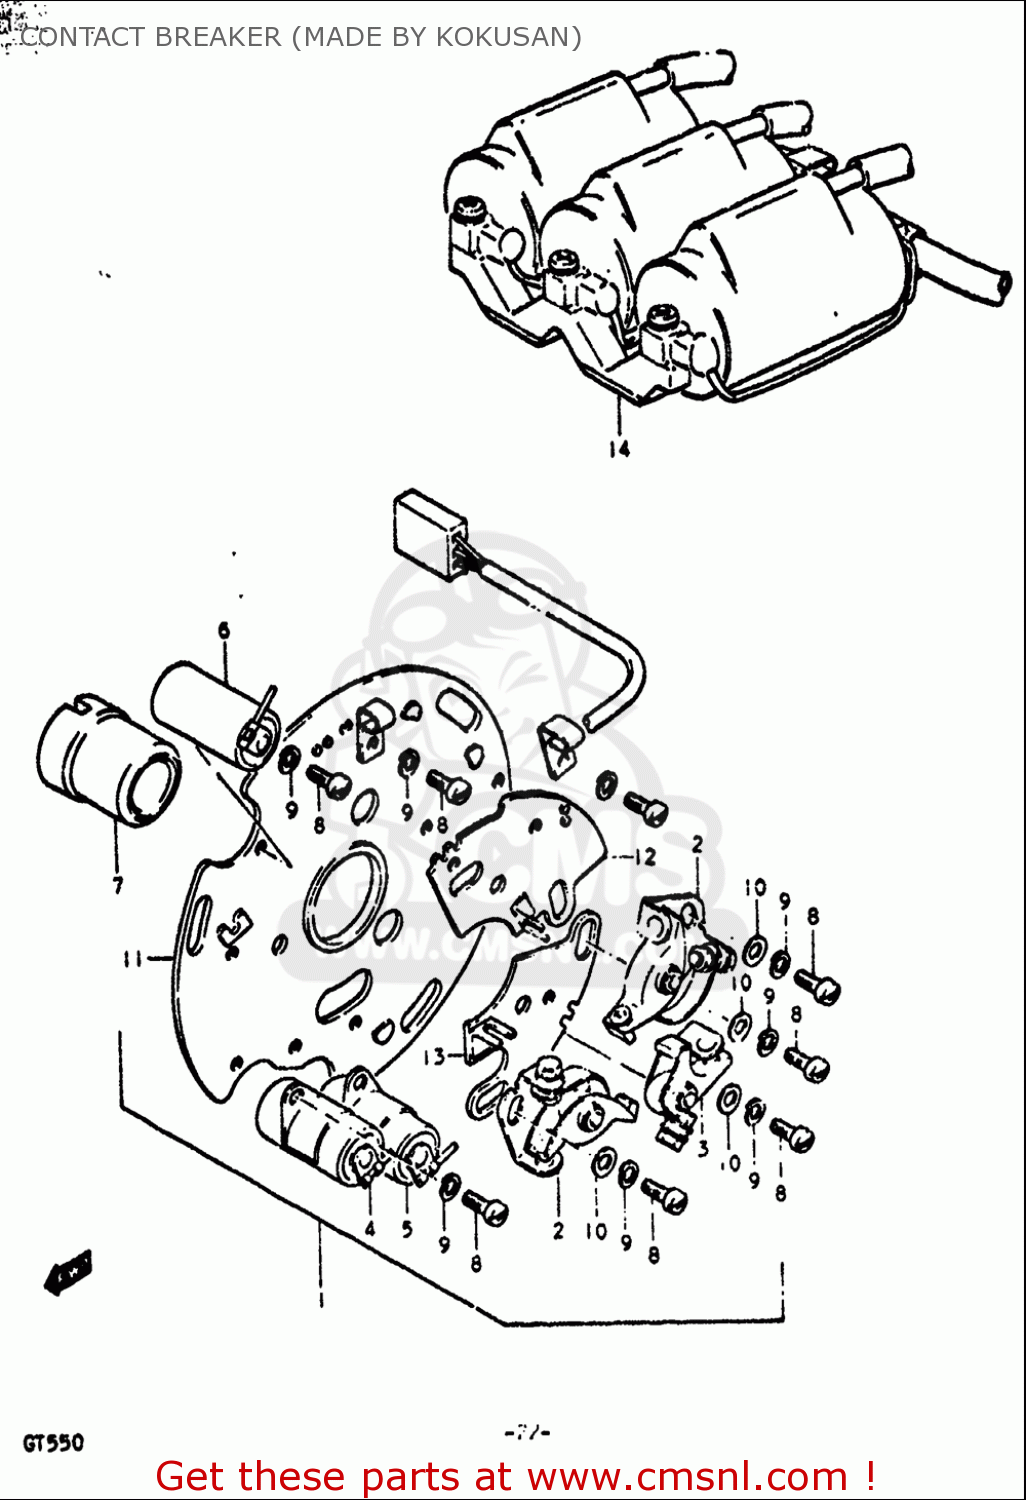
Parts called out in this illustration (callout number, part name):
2	POINT ASSY,R/L
3	POINT ASSEMBLY,CONTACT,MIDDLE
5	CONDENSER, CENTER
8	SCREW 4X6
9	WASHER,LOCK
10	WASHER
